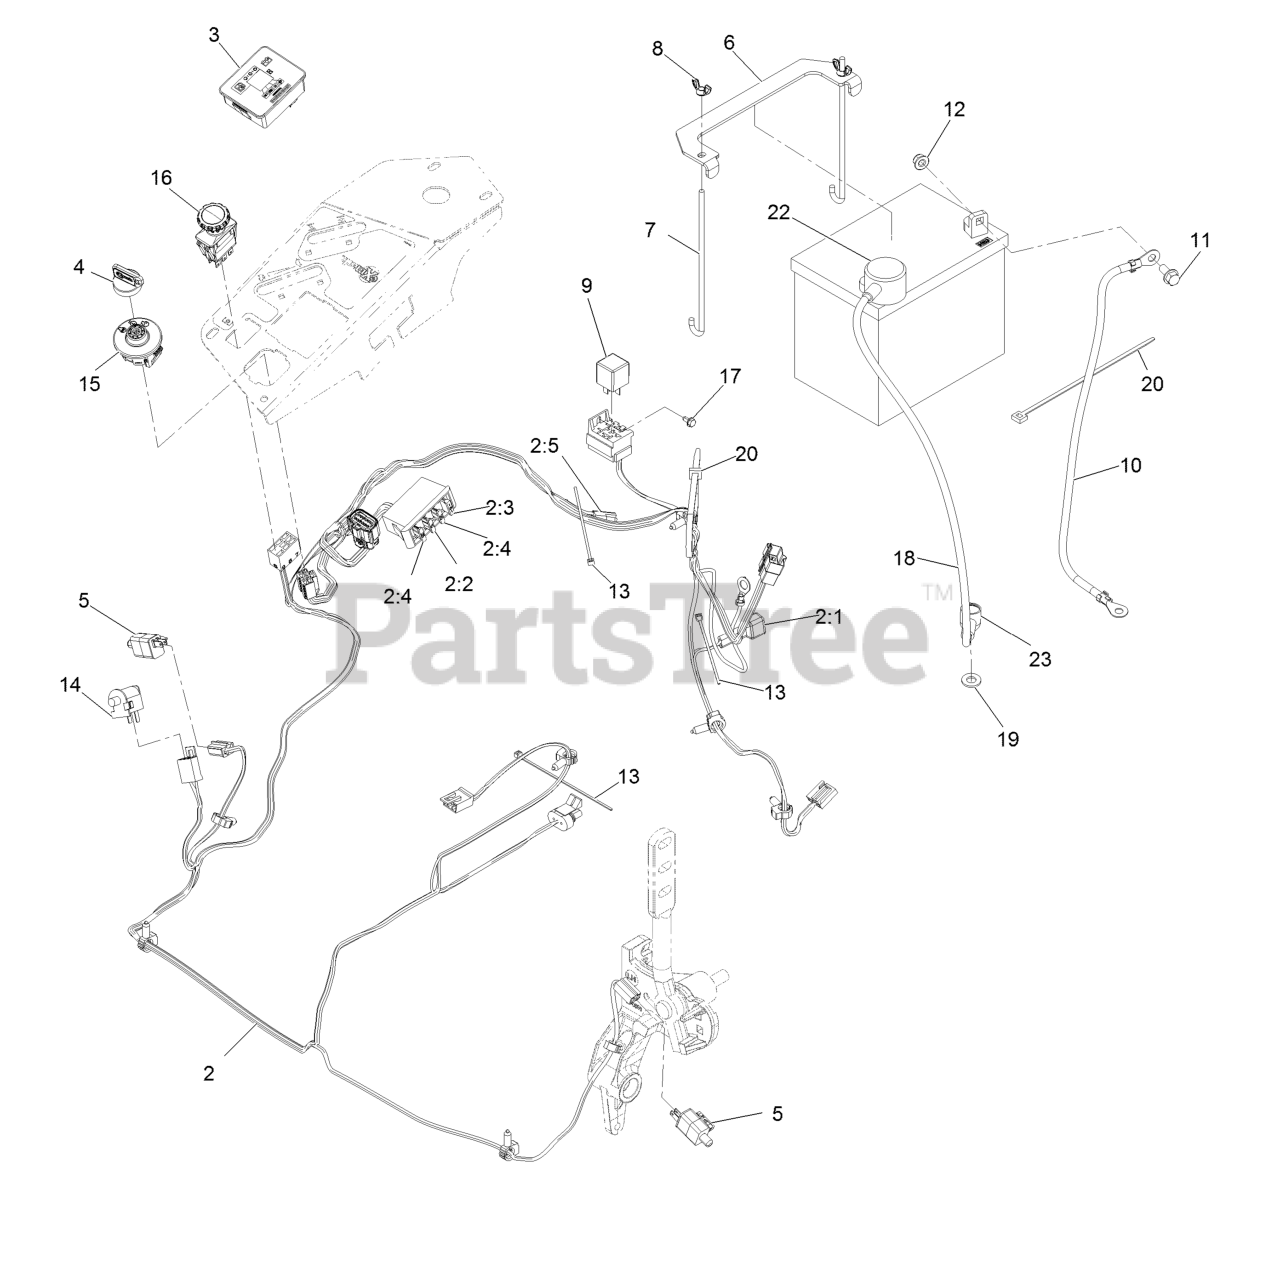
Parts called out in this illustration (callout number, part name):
2	Harness-Wire, Main
2:2	Fuse-Blade, 10 Amp
2:3	Fuse-Blade, 15 Amp
2:4	Fuse-Blade, 25 Amp
2:5	Cap-Plug
3	Fuel/Hour Meter ASM
4	Key-Ignition
4	Key-Exmark Logo
6	Strap-Tie Down, Battery
7	Bolt-Holddown
8	Wingnut-Nyloc 1/4-20
9	Relay-12Vdc 40 Amp
10	Cable-Battery, Negative
11	Screw-HH Flg 5/16-18 X 3/4
12	Nut-Nyloc 5/16-18 Flg
13	Tie-Cable 5 1/2 (Small)
15	Switch-Ignition
16	Switch-PTO, 10 Amp
17	Screw-HWH #10-24 X 3/8
18	Cable-Battery, Positive
19	Washer-3/8 SAE
20	Tie-Cable 7 15/16 (Large)
22	Insulator-Battery
23	Insulator-Solenoid
